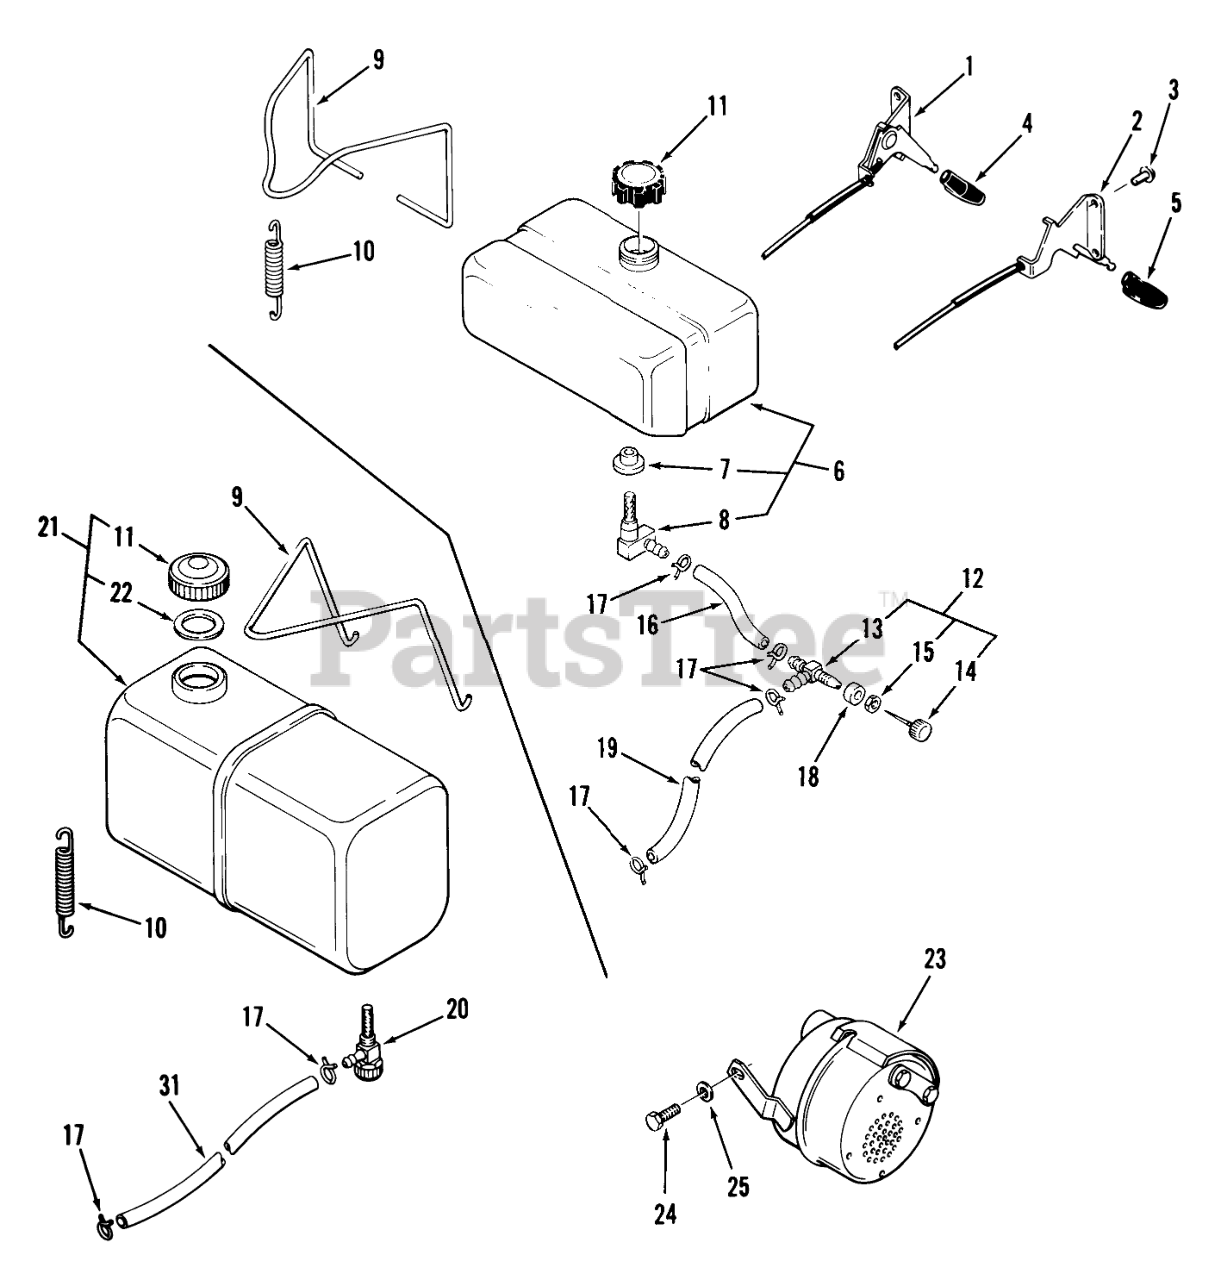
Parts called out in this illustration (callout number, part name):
1	Throttle Control
1	Assy-Choke/Throttle Control
1	CONTROL-THROTTLE
2	CONTROL THROTTLE
2	CONTROL-CHOKE
3	RIVET-4
4	KNOB-THROTTLE
5	KNOB-CHOKE
6	ASSY-FUEL TANK
7	BUSHING
8	FITTING FUEL TANK
9	Hold Down Wire
9	WIRE-HOLD DOWN
10	SPRING-EXTENSION
11	CAP-GASOLINE
11	Gasoline Cap
12	S/A FUEL VALVE
13	VALVE BODY
16	Fuel Hose 3.8 in. (9.7 cm)
17	Clamp
18	SPACER
19	Fuel Hose 18"
20	FILTER & VALVE ASSY
21	Fuel Tank Assy
22	Seal (Service Only)
23	ASSY-MUFFLER
24	Bolt
31	Fuel Hose
31	Fuel Hose 18"
